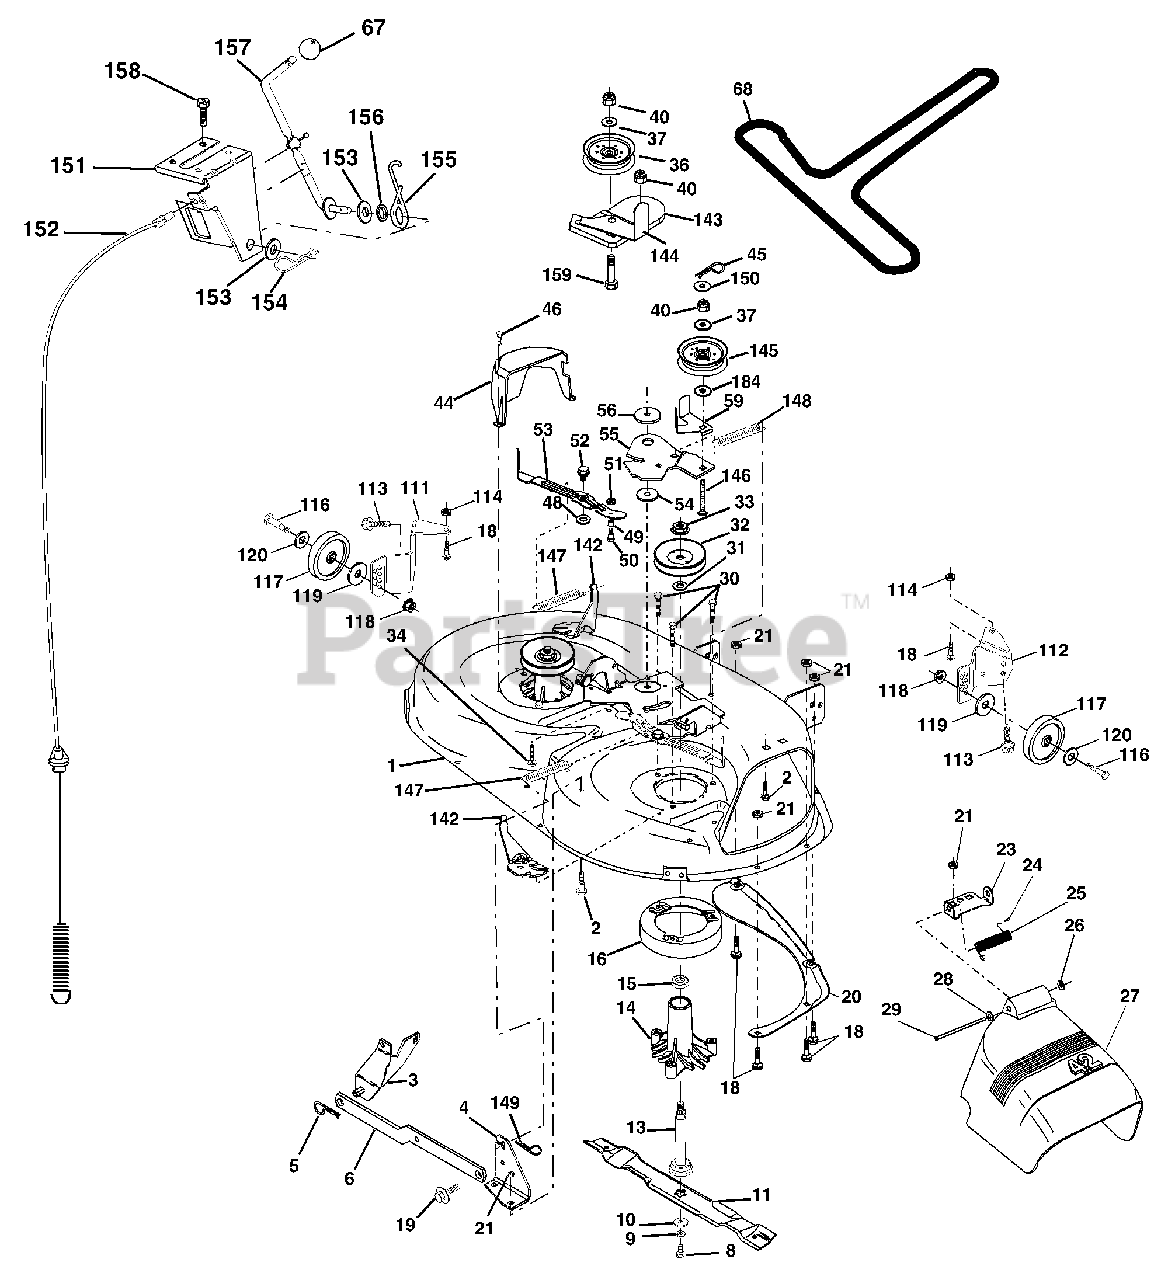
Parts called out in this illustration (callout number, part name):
1	Mower Deck Assembly, 42"
2	Bolt
3	Bracket Asm Fr. Sway Bar 3/42
4	Bracket Asm Deck 42" Sway Bar
5	Retainer Spring
6	Bar Sway Deck
8	Bolt 3/8-24 x 25 Grade 8 patched
9	Washer, Lock
10	Washer, Hardened
11	Blade, 42" Mulching Std
11	Blade, 42" Mulching Premium
11	Blade, 42" Hi-Lift
13	Shaft Assembly, Mandrel, Vented
14	Housing, Mandrel, Vented
15	Bearing, Ball, Mandrel
16	Stripper, Mower Deck
18	Bolt, Carriage 5/16-18 x 5/8
19	Bolt, Shoulder
20	Baffle, Vortex
21	Nut
23	Bracket, Deflector Mower 42"
24	Cap, Sleeve 80 x 112 Blk Mower
25	Spring, Torsion, Deflector 2 52
26	Nut, Push Phos & Oil
27	Shield, Deflector 42" Blk
28	Washer 11/32 x 5/8 x 16 Gauge
29	Rod, Hinge 42" 6 75 W/G
30	Screw Thdrol Hex
31	Washer, Spacer Mower Vented
32	Pulley, Mandrel
33	Nut, Toplock
34	Bolt
36	Pulley, Idler, Flat
37	Washer 13/32 x 13/16 x 16 Gauge
40	Nut
44	Guard, Mandrel, LH
45	Retainer
46	Screw, Thdrol 1/4-20 x 5/8 T
48	Washer, Hardened
49	Roller Assembly, Cam Follower
50	Bolt, Shoulder #10-24 Grade 5
51	Locknut
52	Bolt, Shoulder 5/16-18 UNC
53	Arm Assembly, Pad, Brake
54	Washer, Hardened
55	Arm, Idler
56	Spacer, Retainer
59	Guard TUV Idler
67	Knob
68	V-Belt, 42" Mower
111	Bracket, Gauge, Wheel LH
112	Bracket, Gauge, Wheel RH
113	Screw Tapping 3/8-16 x .625
114	Nut, Keps 5/16 - 18 UNC
116	Bolt, Shoulder
117	Wheel, Gauge
118	Nut Centerlock 3/8-16
119	Washer 3/8 x 7/8 x 14 Ga.
120	Washer 17/32 x 15/16 x 12 Ga.
142	Arm Spring Brake Mower
143	Bracket Arm Idler 42"
144	Keeper Belt 42" Clutch Cable
145	Pulley Idler Flat
146	Bolt Carriage Idler
147	Spring Extension
148	Spring Return Idler
149	Retainer Spring Yellow
150	Washer 9/32 x 3/4 x 16 Ga.
151	Bracket Clutch Cable
152	Clutch Cable 42"
153	Washer Flat 3/8" Type B
154	Spring Retainer
155	Spring Retention LVR CLTCH CAB
156	Spacer Clutch Cable
157	Rod Clutch Cable 3/8"
158	Screw Hex Thd Cut 1/4-20 x 1/2
159	Bolt Rdhd Sqn 3/8-16 UNC x 1-3/4
184	Washer
